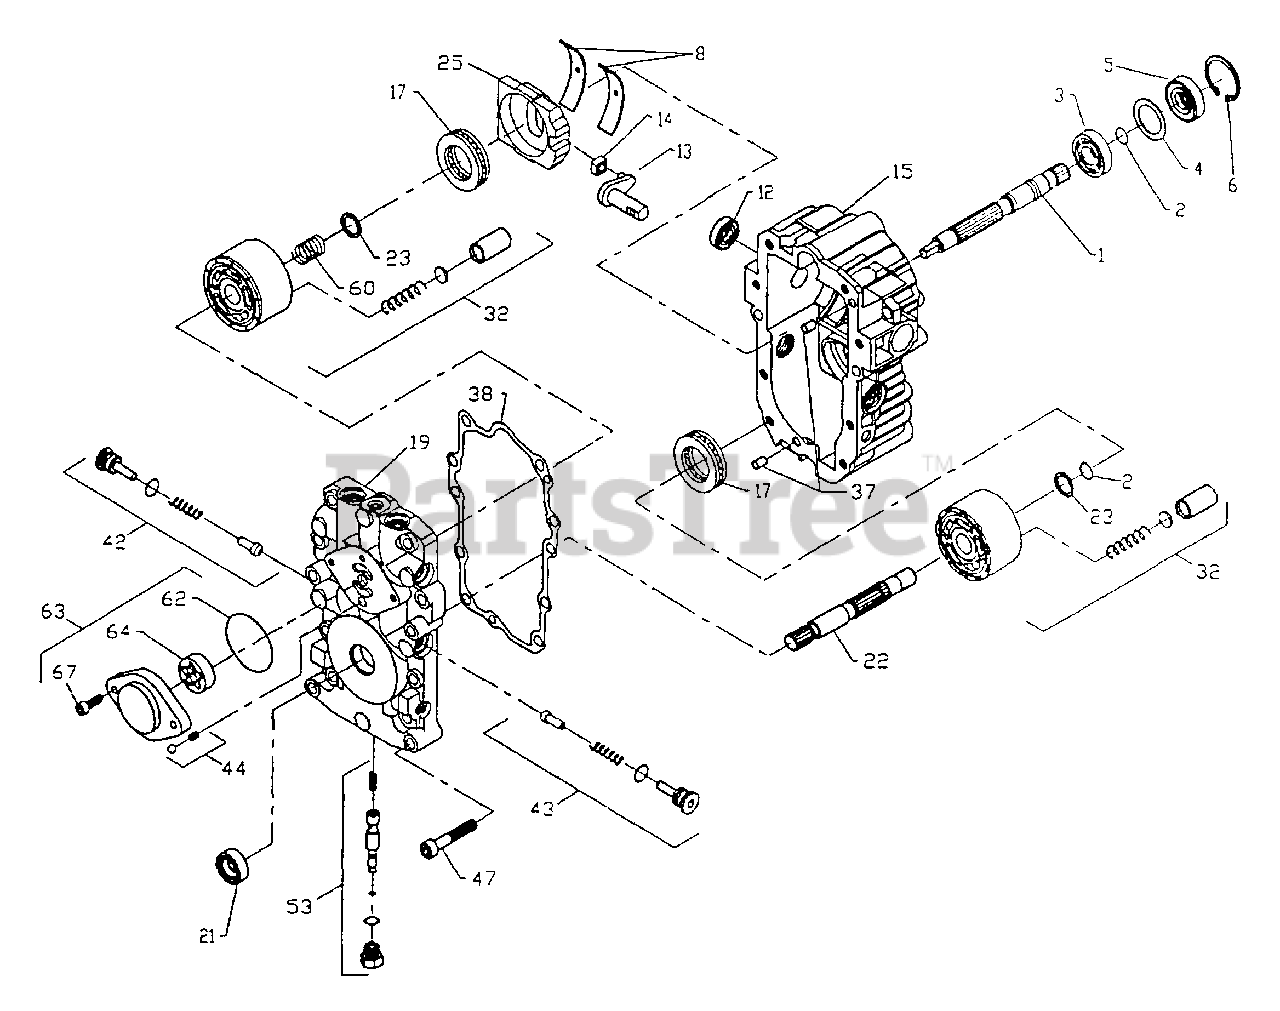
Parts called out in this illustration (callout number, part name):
1	Shaft, Pump
2	Ring, Retaining (AYP part number)
3	Bearing, Ball
4	Spacer (outside vendor part)
5	Seal, Lip (AYP part number)
6	Ring, Retaining (AYP part number)
8	Bearing, Cradle (AYP part number)
12	Seal, Lip (AYP part number)
13	Arm, Trunnion
14	Guide, Slot
15	Housing Kit, Transmission
17	Bearing, Thrust, Ball (AYP part number)
19	Center Section Kit
21	Seal, Lip
22	Shaft, Motor
23	Washer, Block Thrust
25	Swashplate, Variable
32	Block Assembly (AYP part number)
37	Pin, Stainless, Headless
38	Gasket, Center Section
42	Check Valve Kit
43	Check Valve Kit
44	Charge Relief Kit
47	Screw, Socket Head, Cap
53	Bypass Valve Kit
60	Block Spring
62	O-Ring
63	Charge Pump Kit
64	Gerotor Assembly
67	Screw, Socket Head, Cap
